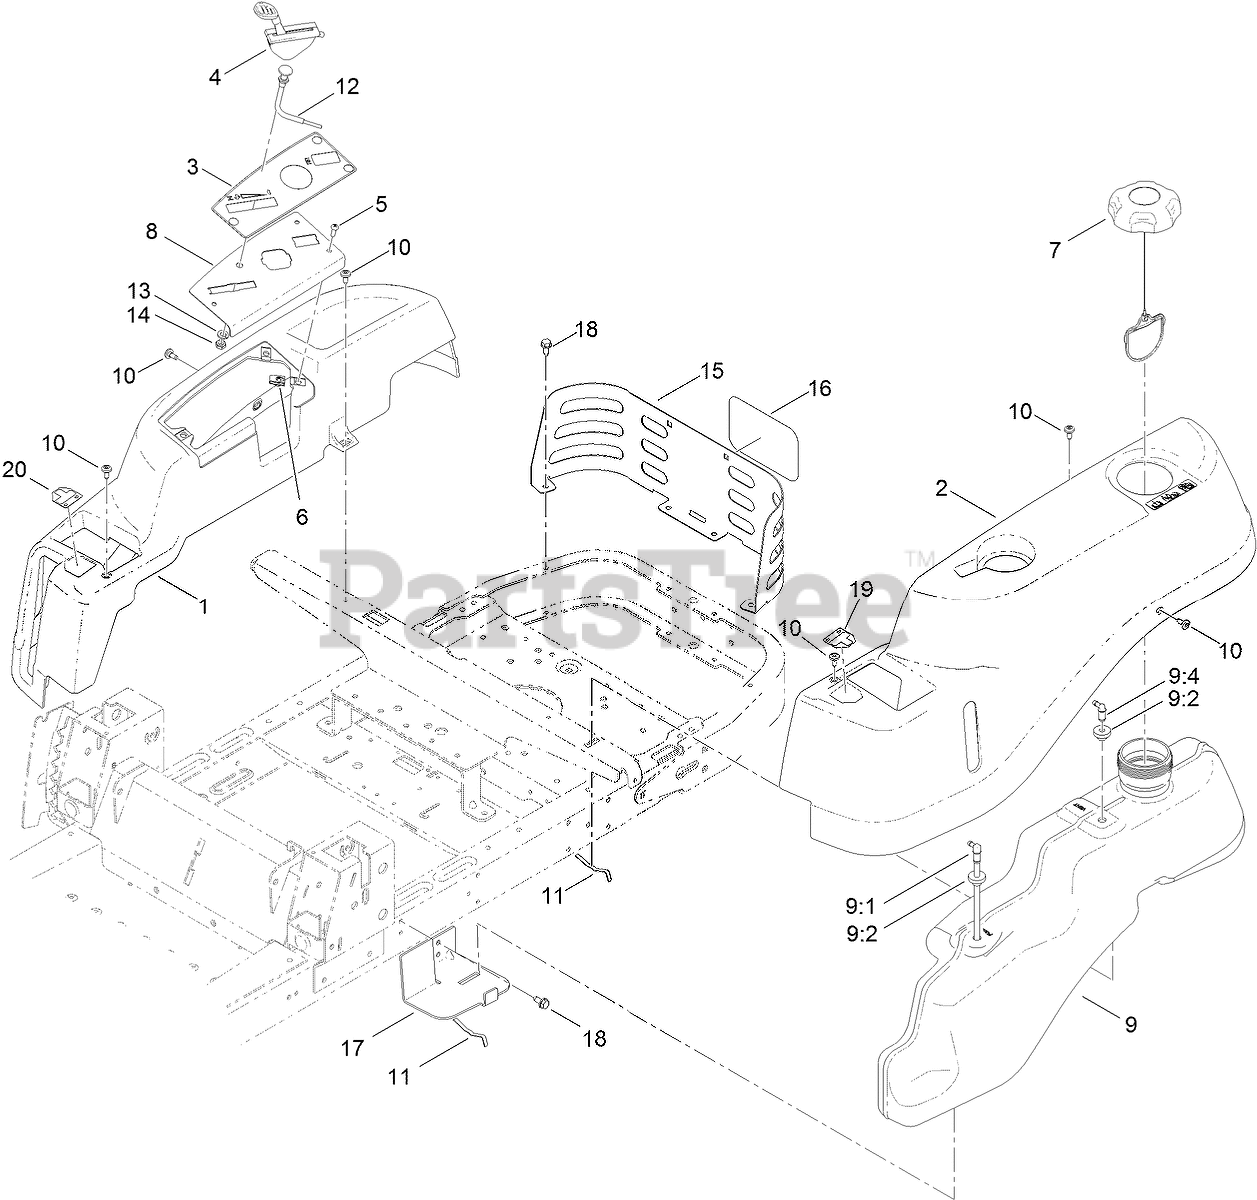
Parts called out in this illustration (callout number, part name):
1	POD-RH
2	POD-LH
3	DECAL-PANEL, CONTROL
4	CABLE-THROTTLE
5	SCREW-PRH
7	CAP-FUEL, RATCHETING
8	PLATE-CONTROL
9	FUEL TANK ASM
9:1	CONNECTOR-ELBOW, 90 DEG
9:2	BUSHING
9:4	FITTING-PLASTIC
10	SCREW-SHOULDER
11	SPRING
12	CABLE-CHOKE
13	WASHER-LOCK
14	NUT-HJ
15	GUARD-REAR
17	SUPPORT-TANK, FRONT
18	SCREW-HWHTF
19	DECAL-CONTROL LEVER, LH
20	DECAL-CONTROL LEVER, RH
